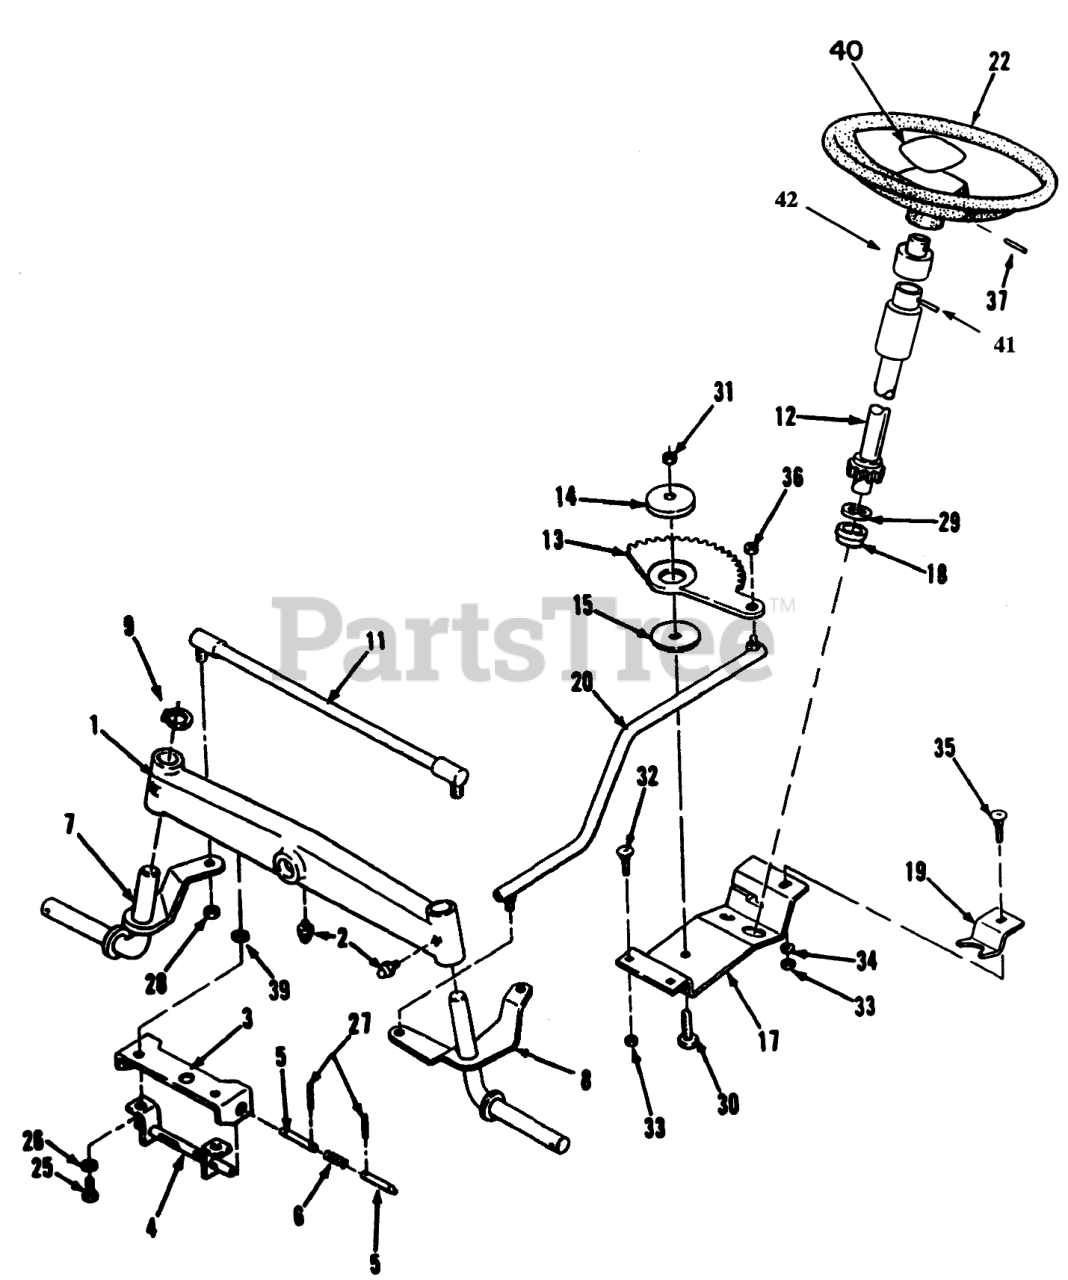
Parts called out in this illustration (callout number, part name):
1	AXLE-FRONT R
2	FITTING-GREASE
3	BRACKET-SUPPORT R
4	TUBE & BRACKET ASM R
6	SPRING
7	ASSY ARM STEERING R
8	ASSY ARM STEERING R
9	RING-RETAINING
11	ASS'Y-TIE ROD R
12	WLDMT-STRING SHFT B
13	GEAR SECTOR
14	BUSHING
15	WASHER-BEARING
17	BRKT-STEERING GEA R
18	BEARING-WHEEL
19	RETAINER R (NS)
20	ASSY BALL JOINT L R
22	STR'G-WHL 13" TORO
25	SCREW-HH
26	WASHER-LOCK
27	PIN-SPRING
28	Nut-Lock
29	SHIM-WASHER
30	SCREW-CARR
32	SCREW-CARR
33	SCREW-CARR
34	WASHER-PLAIN
35	BOLT-CARR
36	NUT-6
37	SPIROL PIN 5/16X13/8
39	WASHER
40	STRG-WHL INSERT TORO
41	PIN-ROLL
42	SHAFT-COUPLER
